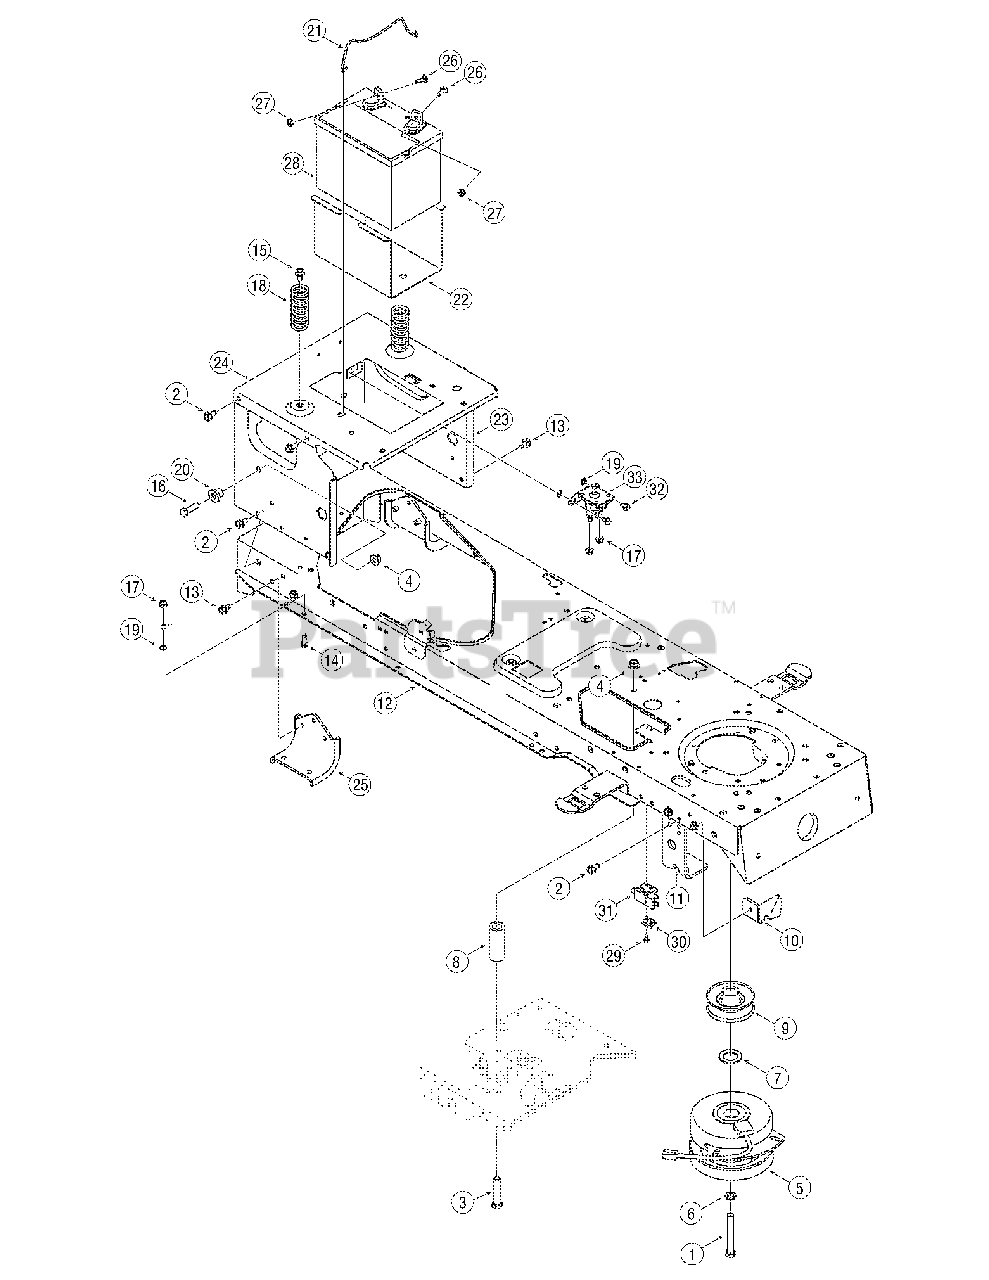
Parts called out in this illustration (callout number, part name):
1	HH Cap Screw 7/16-20 x 3.50
2	AB Screw 5/16-12 x.750
3	HH Cap Screw 3/8-16 x 2.25
4	Flange Lock Nut 3/8-16
5	PTO Clutch, Electric
6	Lock Washer 7/16
7	Flat Washer 1.031 x 1.620 x.095
8	Spacer.385 x.635 x 1.54
9	Electric PTO Engine Pulley
14	TT Screw 1/4-20 x.750
15	LD Screw 5/16-18 x.750
16	HH Cap Screw 3/8-16 x 1.25
17	Flange Lock Nut 1/4-20
18	Compression Spring 1.28 x 3.125
19	Lock Washer 1/4
20	Shoulder Spacer.38 x 1.0 x.70
21	Battery Rod
26	Carriage Screw 1/4-20 x.75
27	Sems Nut 1/4-20
28	Battery 235 CCA
29	AB Screw #10-16 x.50
30	Switch Plate
31	Interlock Switch
32	TT Screw 1/4-20 x.50
33	Solenoid 12V 100 Amp
